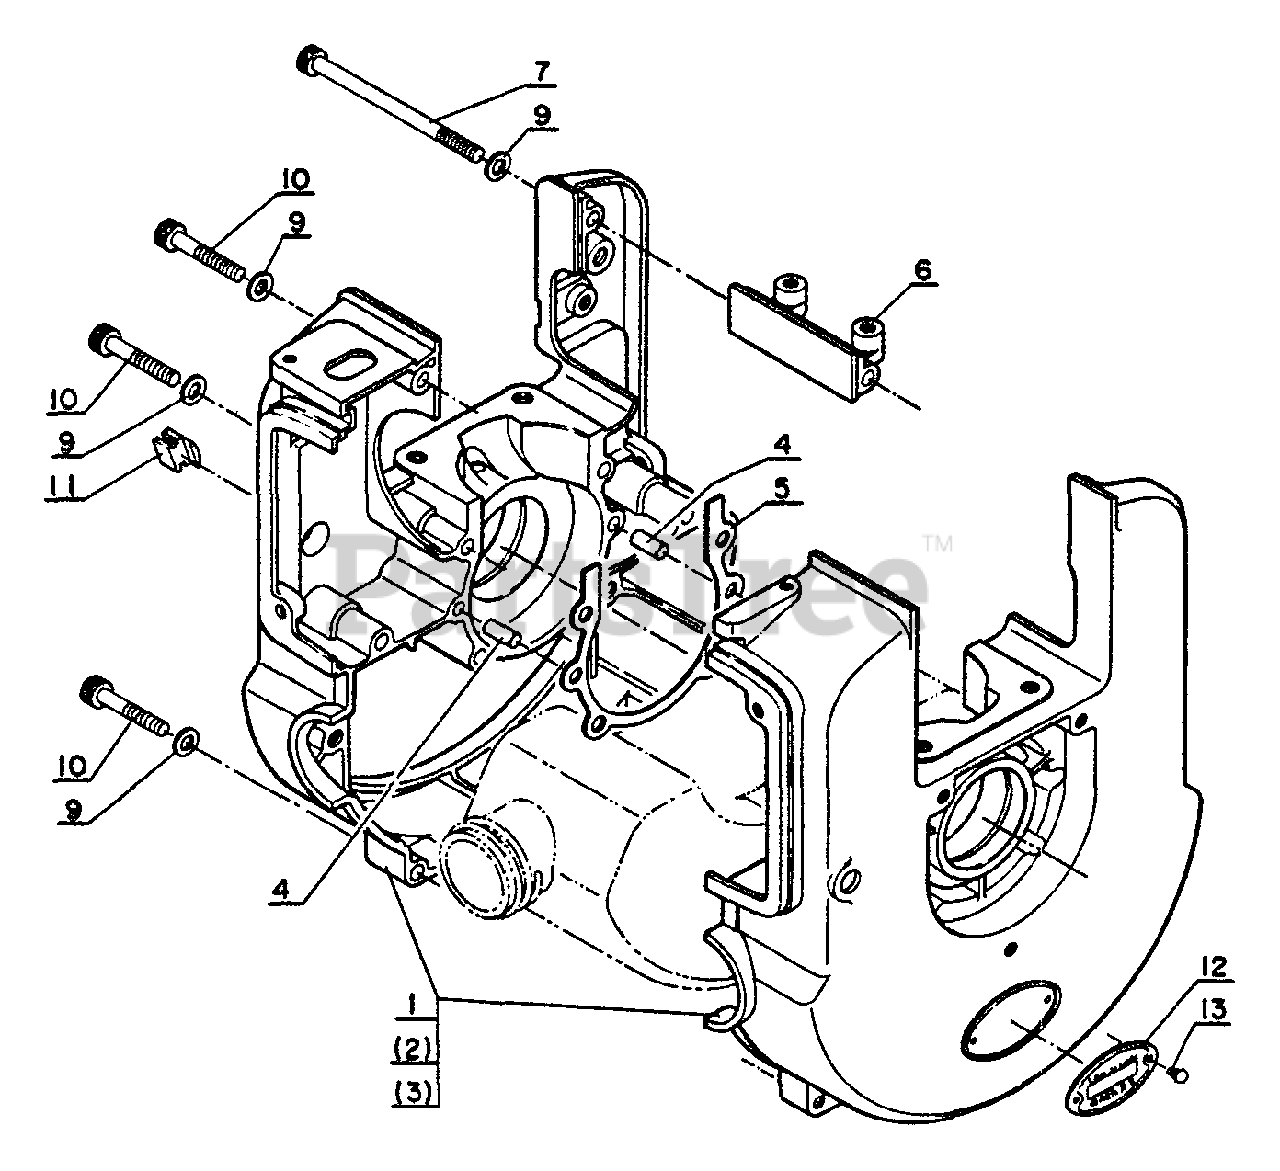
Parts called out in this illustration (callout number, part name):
1	CRANKCASE KIT
4	PIN - LOCATING
5	GASKET, CRANKCASE
6	BRACKET, MUFFLER
7	SCREW - 4X65
9	WASHER - 4
10	SCREW - 4X25
11	PLUG
12	PLATE, MODEL
13	RIVET
